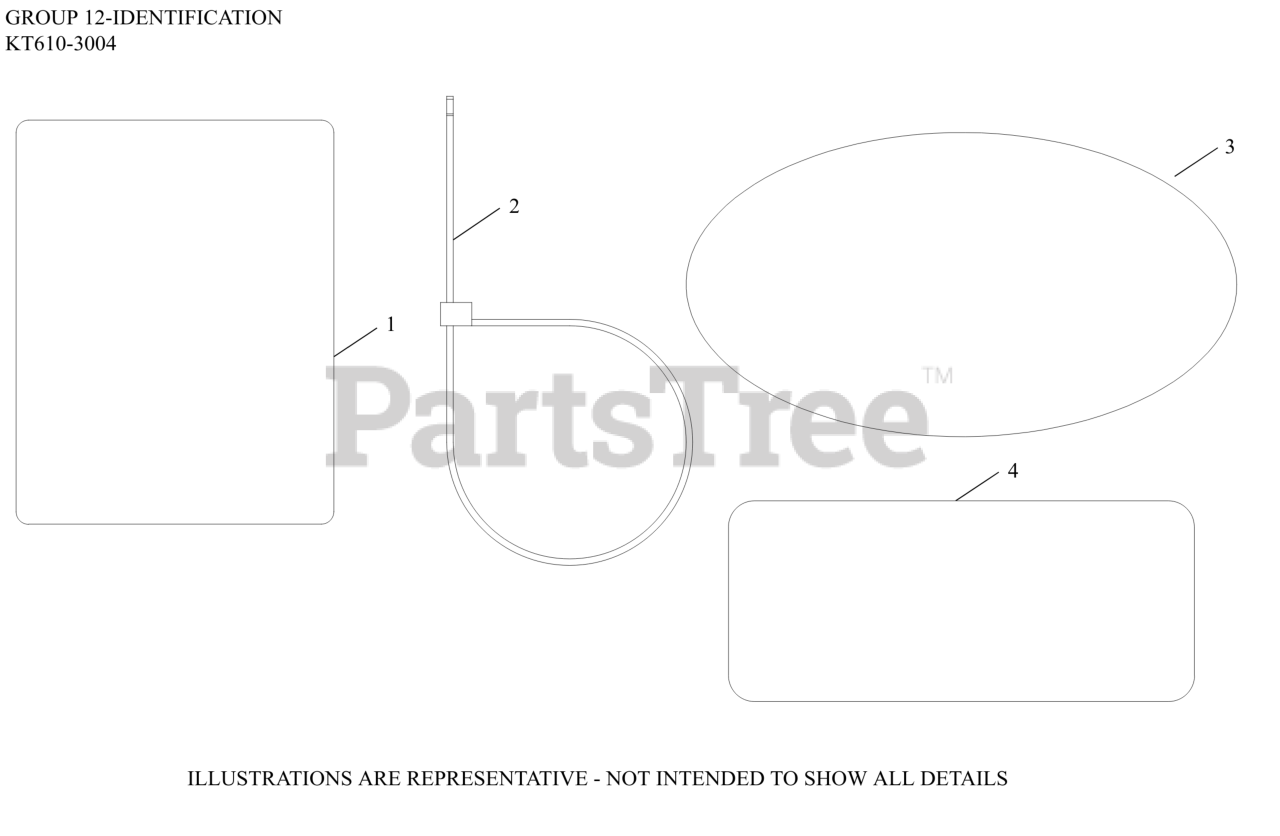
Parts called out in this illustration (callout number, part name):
1	LABEL, CLEAR LAMINATION
3	LABEL, 6600 SERIES (19HP)
3	LABEL, PRO PERFORMANCE FILTRATION SYSTEM
4	LABEL, CANADIAN COMPLIANCE
